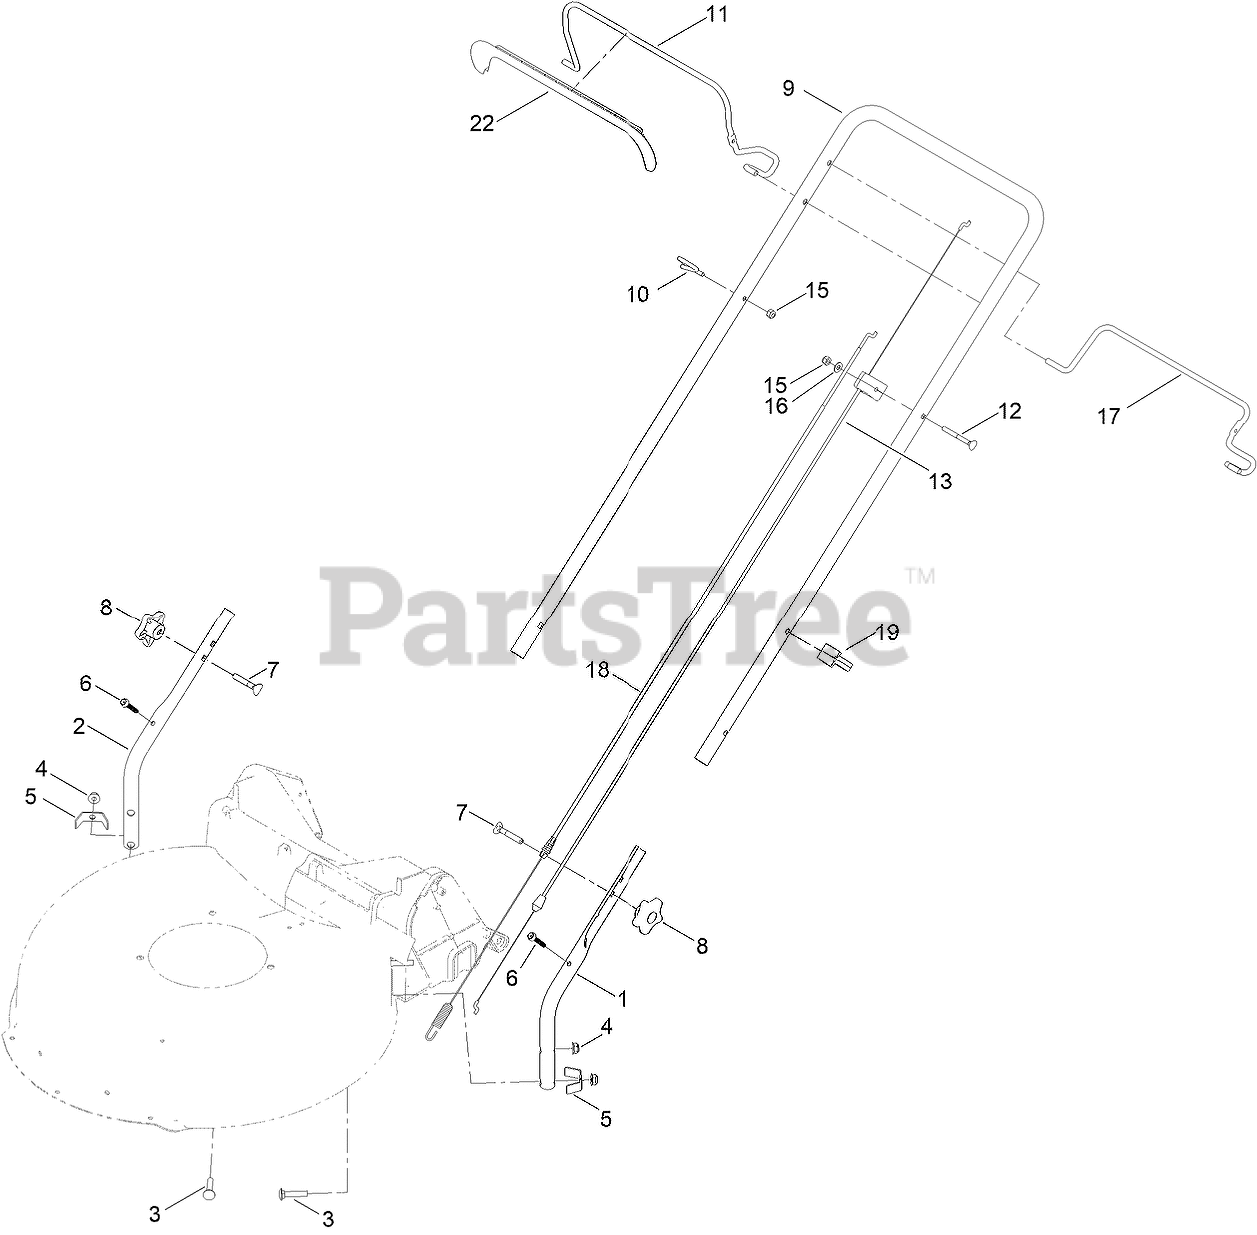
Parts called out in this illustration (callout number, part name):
1	HANDLE-LOWER, LH
2	HANDLE-LOWER, RH
3	BOLT-CARR
4	NUT-FLANGE, NI
5	BRACKET-CHUTE
6	SCREW-FLANGE, SERRATED
7	SCREW-HANDLE
8	KNOB-HANDLE
9	HANDLE-UPPER
10	GUIDE-ROPE
11	BAIL-BRAKE
12	SCREW-HANDLE
13	CABLE-BRAKE
15	NUT-LOCK, NI
16	WASHER-FLAT
17	BAIL-TRACTION
18	CABLE-TRACTION
19	GUIDE-CABLE
22	COVER-BAIL
